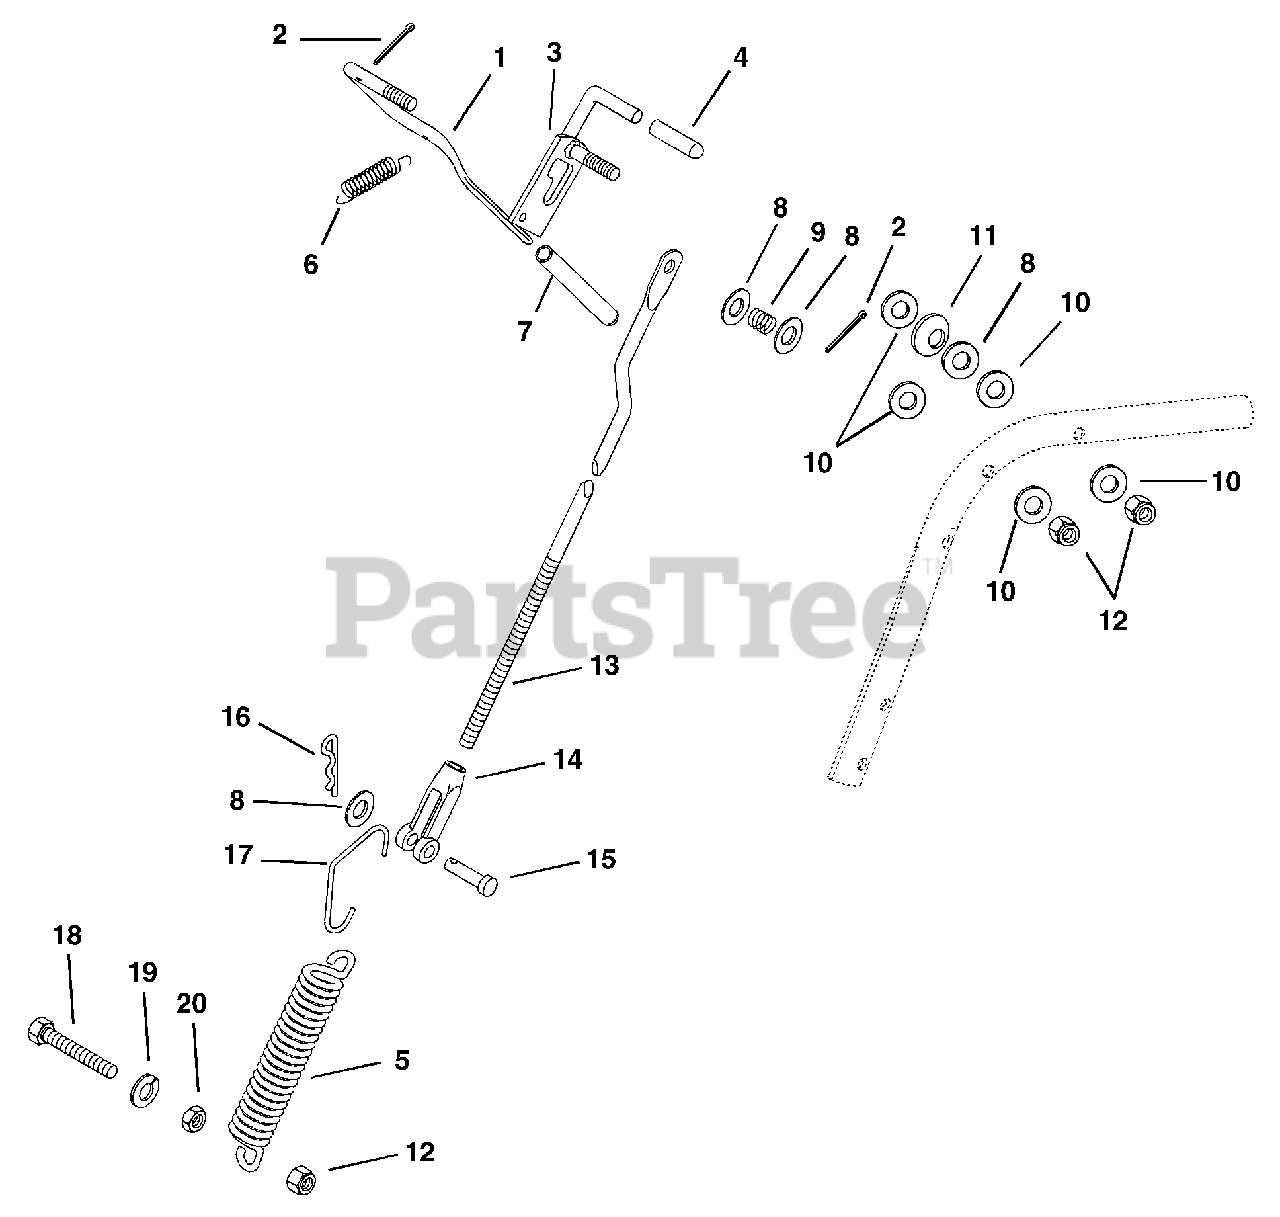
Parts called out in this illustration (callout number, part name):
1	LEVER, HAND CONTROL LH
2	BRAKE CONTROL - 350 SX, 450 SX
3	SG-TENS .041X.500X1.750
4	TIP - BRAKE LOCK LEVER
5	SG-TENS .105X1.00X5.0
6	SG-TENS .041X.500X1.750
7	GRIP,HAND CLUTCH LEVER
8	@WSHR-FL-STL.406X.812X.065 YWZ
9	SG-COMP .045X.600X.750 WLD7.5
10	WSHR-FL-NY .375X.75X.060
11	WSHR-SG .375 ID
12	NUT-JAM .50-13 YWZC
13	ROD,PUMP CONTROL
14	CLEVIS, .38-24 ADJ.
15	PIN-CLEV .38X1.25 YWZC
16	PIN-HAIR INT .08X.18X1.18 YWZC
17	HOOK,SPRING
18	@BLT-HEX .38-16X2.50 GR5 YWZC
19	@WSHR-LK .38X.094 REG YWZC
20	@NUT-HEX .38-16 YWZC
